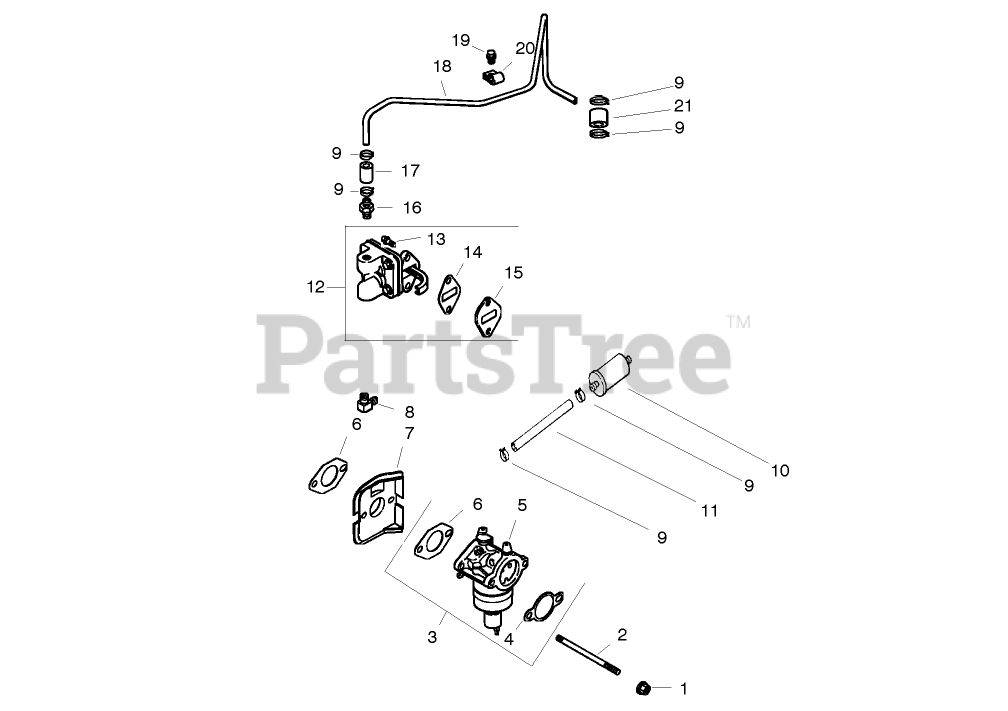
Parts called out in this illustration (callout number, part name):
1	NUT-FLANGE (M6X1.0)
2	Stud (M6x1.0x116)
3	Kit, carburetor w/gaskets (Includes 4, 5, 6 [qty. 1], Terminal 25 452 20-S, Tie 12 454 03-S)
4	Gasket-Base, Air Cleaner
5	Carburetor ASM
6	Gasket-Carburetor
7	Deflector-Heat
8	Connector-Hose, 90 Deg
9	CLAMP-HOSE, SPRING (1/2)
10	Filter-Fuel
11	Line-Fuel (3in)
12	Kit-Pump (Incl 13-15)
13	SCREW-HHFTF (M6X1.0X20)
14	Gasket-Pump, Fuel
15	Spacer-Pump, Fuel
16	Connector-Hose, Straight
17	Line-Fuel (1-1/4in)
18	Line-Fuel. Metal
19	SCREW-HHFTF (M5X.80X10)
20	CLAMP-INSULATED
21	Line-Fuel (2-1/2in)
